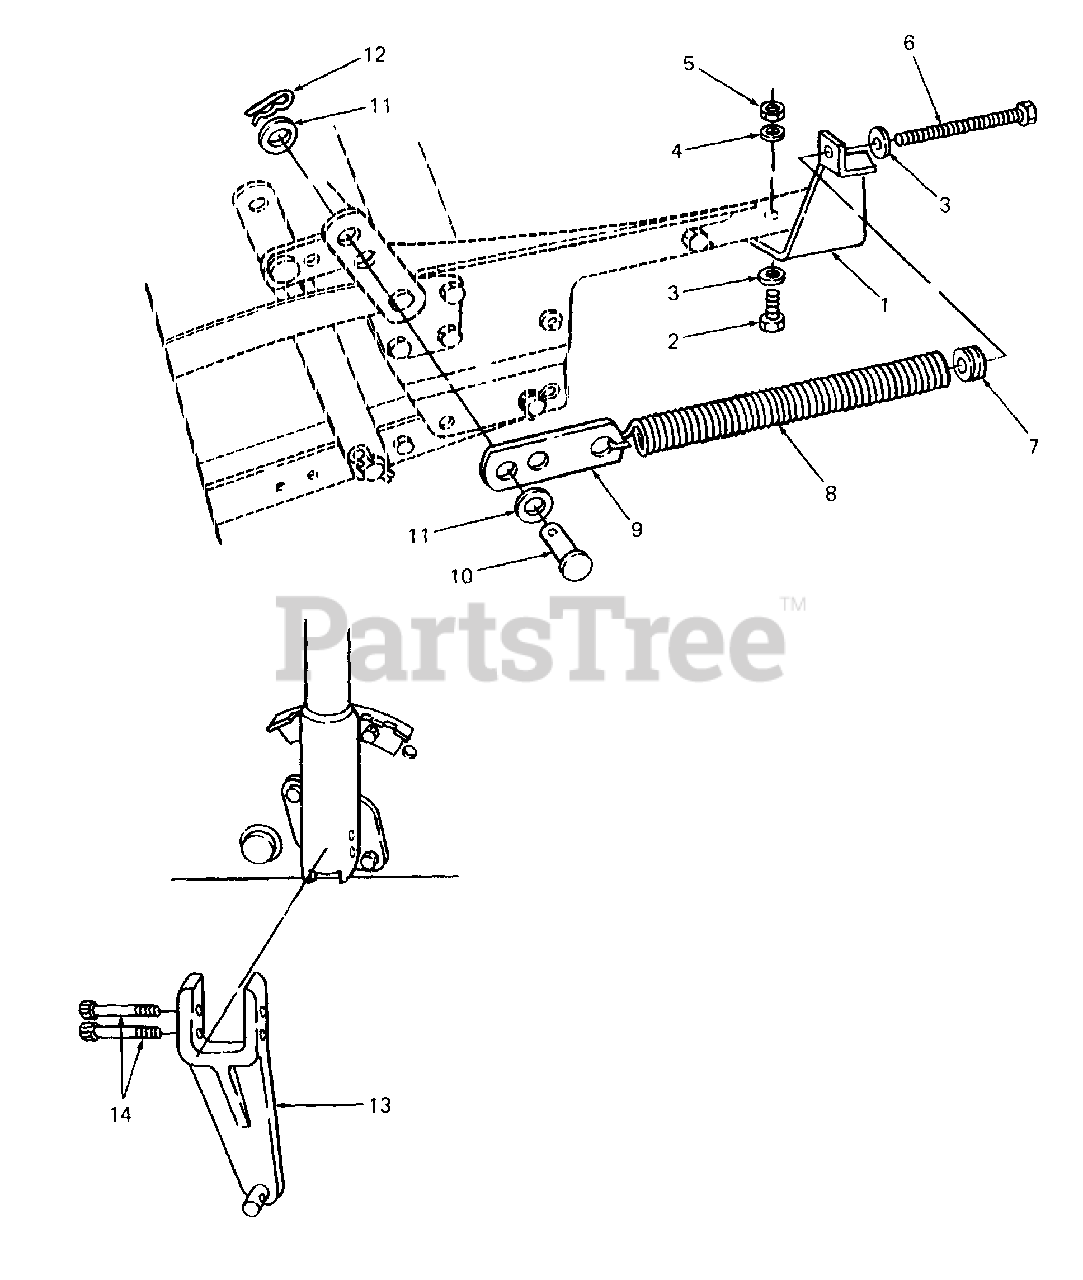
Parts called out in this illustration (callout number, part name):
1	Bracket, Helper Spring
2	Screw, Hex Cap, 3/8-16 X 1.0 Lg
3	Washer, Bell
4	Washer, Flat, .406 X 1.25 X .172 Thk
5	Nut, Hex, 3/8-16
6	Screw, Hex Special
7	Insert, Spring
8	Spring, Extension
11	Washer, Flat, .635 X 1.00 X .067 Thk
12	Pin, Internal Cotter
13	Bracket, Manual Lift
14	Screw, Socket Head
